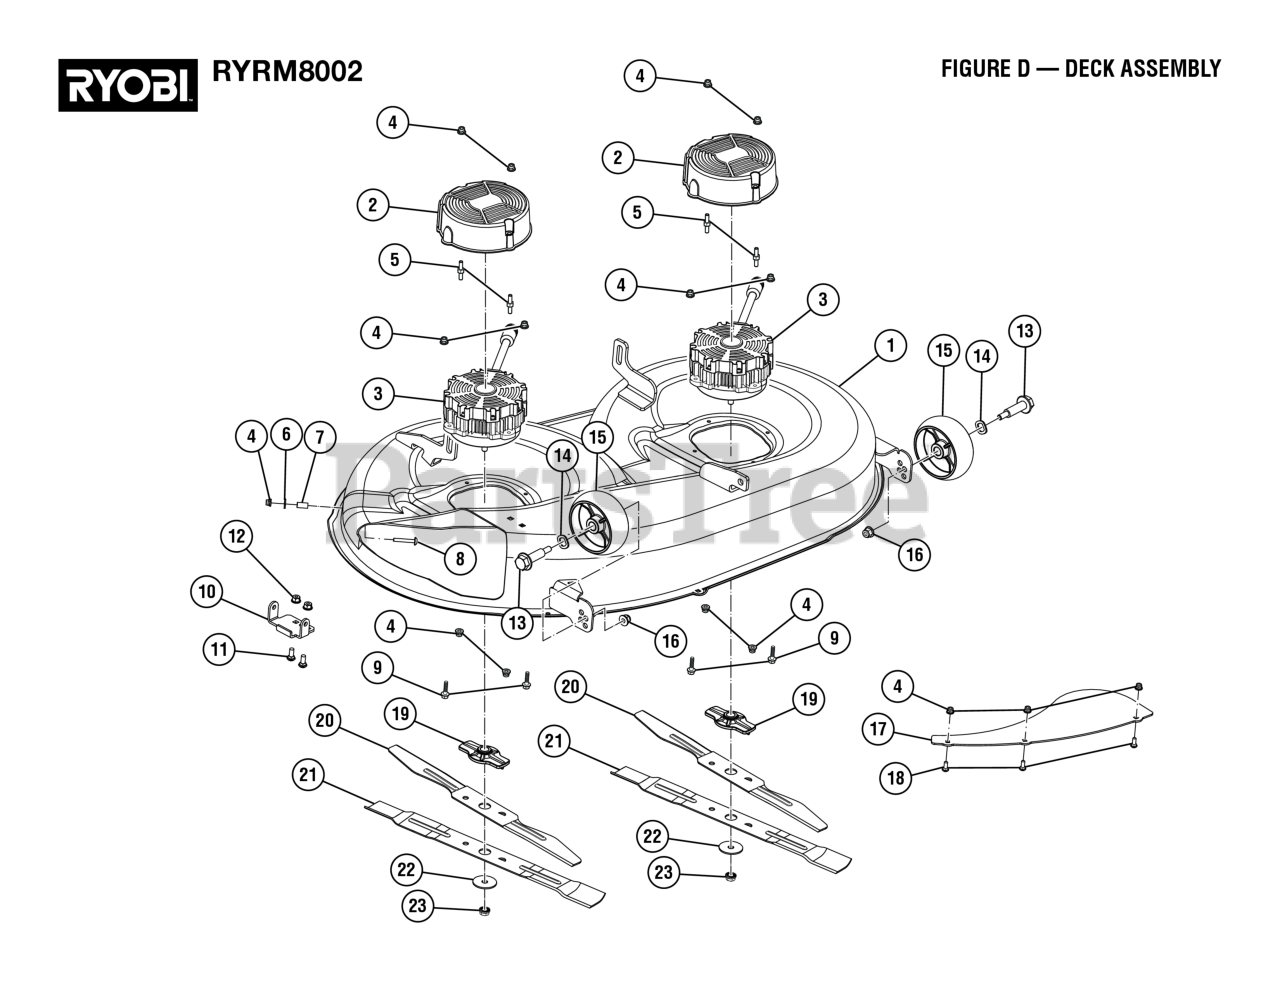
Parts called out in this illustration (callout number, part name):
1	Deck, 42 in
2	Motor Cover
3	Deck Motor
4	Flange Lock Nut (M6 x 1.00)
5	Stud (M6)
6	Washer (OD18 x ID6.4 x 1.6t)
7	Deck Bagger Chute Mounting Shaft
8	Screw (M6 x 40, Soc Hd.)
9	Flange Bolt (M6 x 25 mm, Hex Hd.)
10	Deck Bracket
11	Carriage Bolt (M8 x 20 mm)
12	Flange Nut (M8) (For Drive Motor Controller V)
13	Shoulder Bolt (M10 x 70 mm)
14	Spring Washer (OD20.5 x ID17 x 0.3t)
15	Front Deck Roller Wheel (124.5 Dia.)
16	Flange Lock Nut (M10 x 1.25)
17	Deck Baffle (42 in.)
18	Carriage Bolt (M6 x 16 mm)
19	Crosscut Blade Adapter
20	21 in. Top Blade, Stepped
21	21 in. Blade
22	Blade Retainer Washer
23	Flange Lock Nut (M10 x 1.25)
